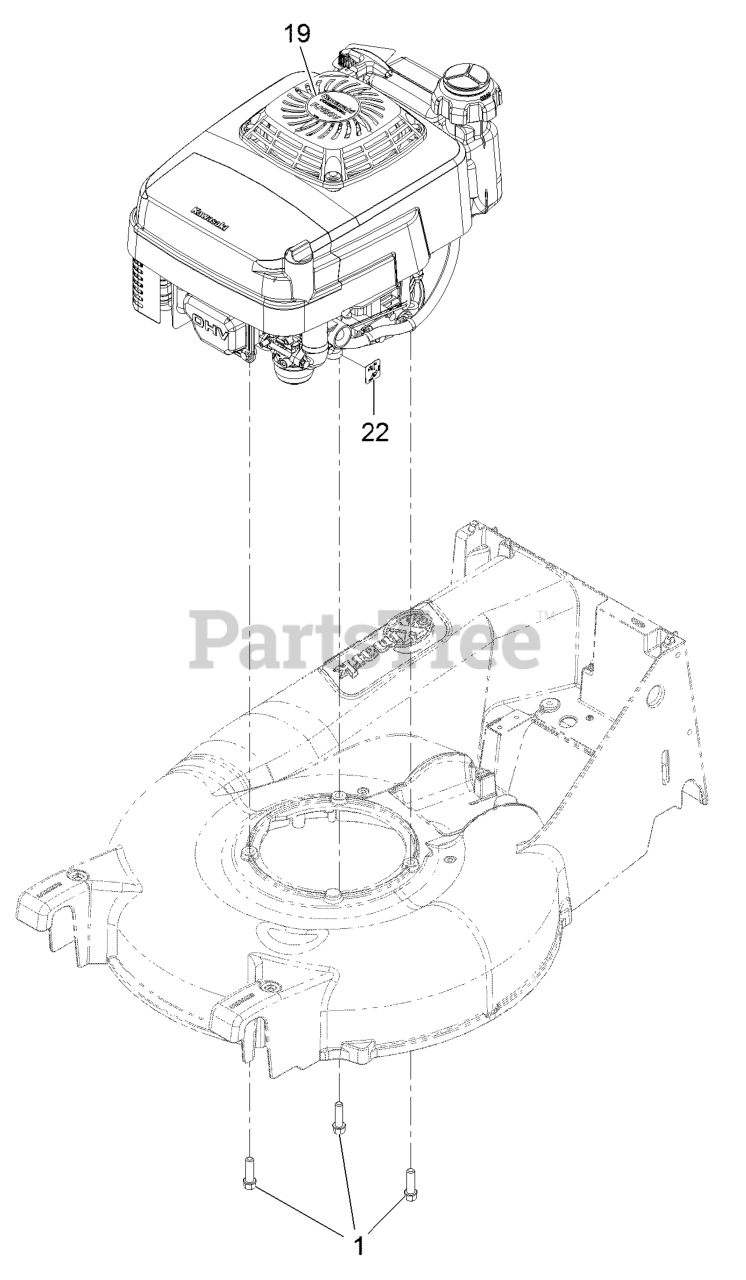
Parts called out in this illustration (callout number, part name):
1	SCREW-TAPTITE
19	DECAL-RECOIL
22	DECAL-PRIMER
